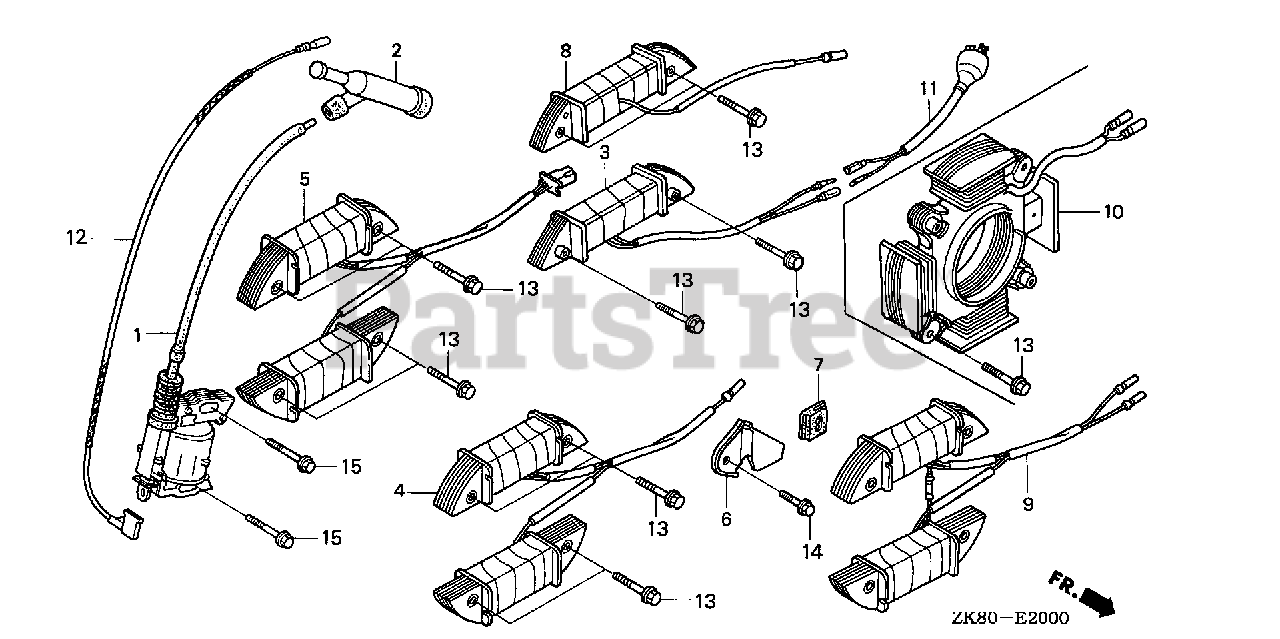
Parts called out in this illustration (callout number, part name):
1	COIL ASSY., IGNITION
2	CAP ASSY., NOISE SUPPRESSOR
12	WIRE, STOP SWITCH (370MM)
15	BOLT, FLANGE (6X25) (CT200)
